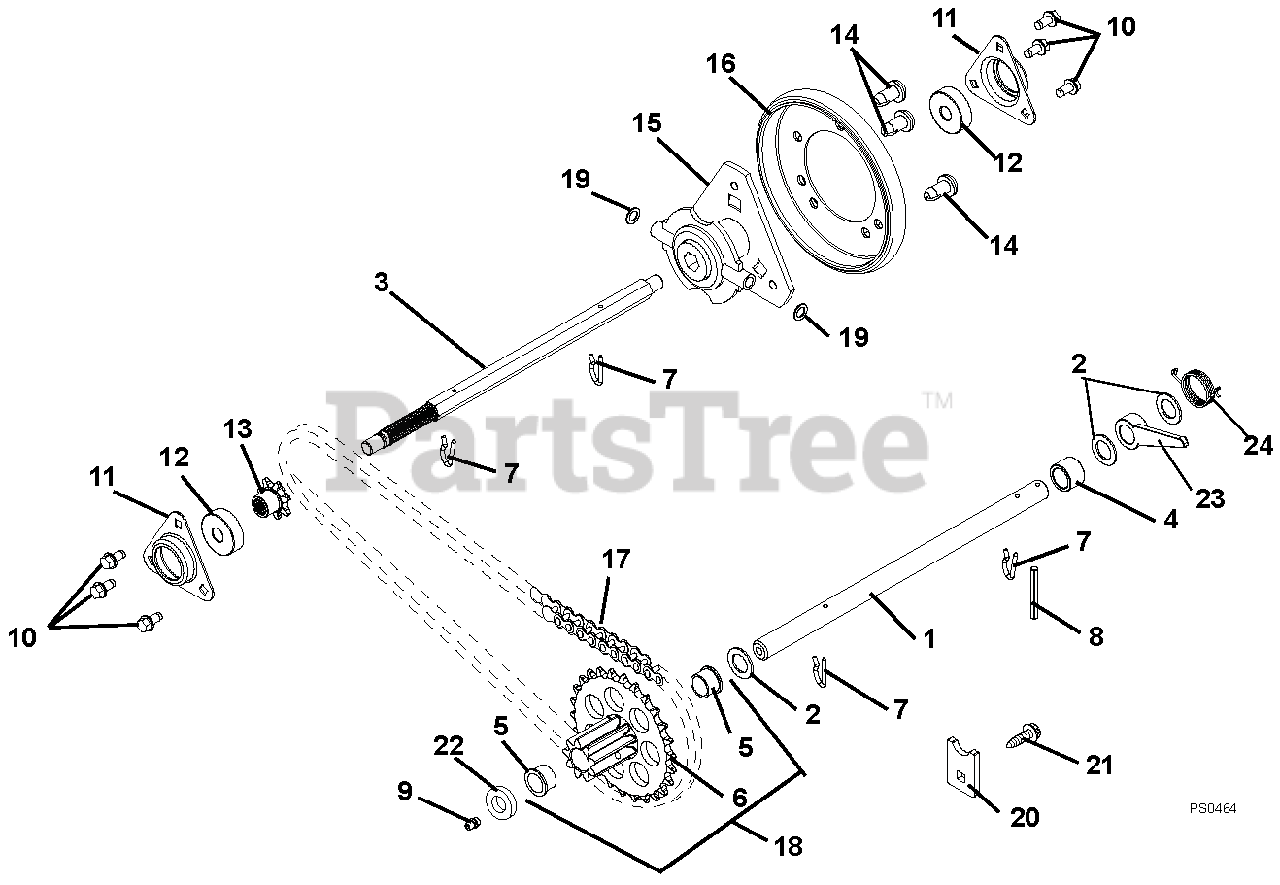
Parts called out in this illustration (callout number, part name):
1	SHAFT, PINION
2	WSHR-FL-STL .630X1.005X.062 YZ
3	SHAFT, HEX-W/SPLINE
4	SPACER, .635X.880X.611
5	BSHG-FLG .625X.750X.500X.875
6	PINION & SPROCKET
7	PIN, SPRING CLIP
8	PIN-ROLL .125X1.00
9	ZERK,FITTING .25X.125 DRIVE IN
10	@SCR-TAP .25-20X.50 HWH TR YWZ
11	FLANGE, BEARING
12	BRG-BALL .437X1.375X.437
13	SPROCKET, PINION 7T W/SPLINE
14	SCR-TAP SERRDHDTX .31-18X.50BP
15	CARRIER, DRIVE DISK
16	FRICTION, DISC
17	CHAIN - #41, 32 PITCHES
18	PINION & SPROCKET W/BUSHINGS
19	WSHR-FL-STL .505X1.00X.062YWZC
20	TAB, ANTI ROTATION
21	@SCR-TAP .25-20X.50 HWH TR YWZ
22	BSHG-SLV, .635X.880X.305
23	LEVER, LOCK ARM
24	SPRING, TORSION
